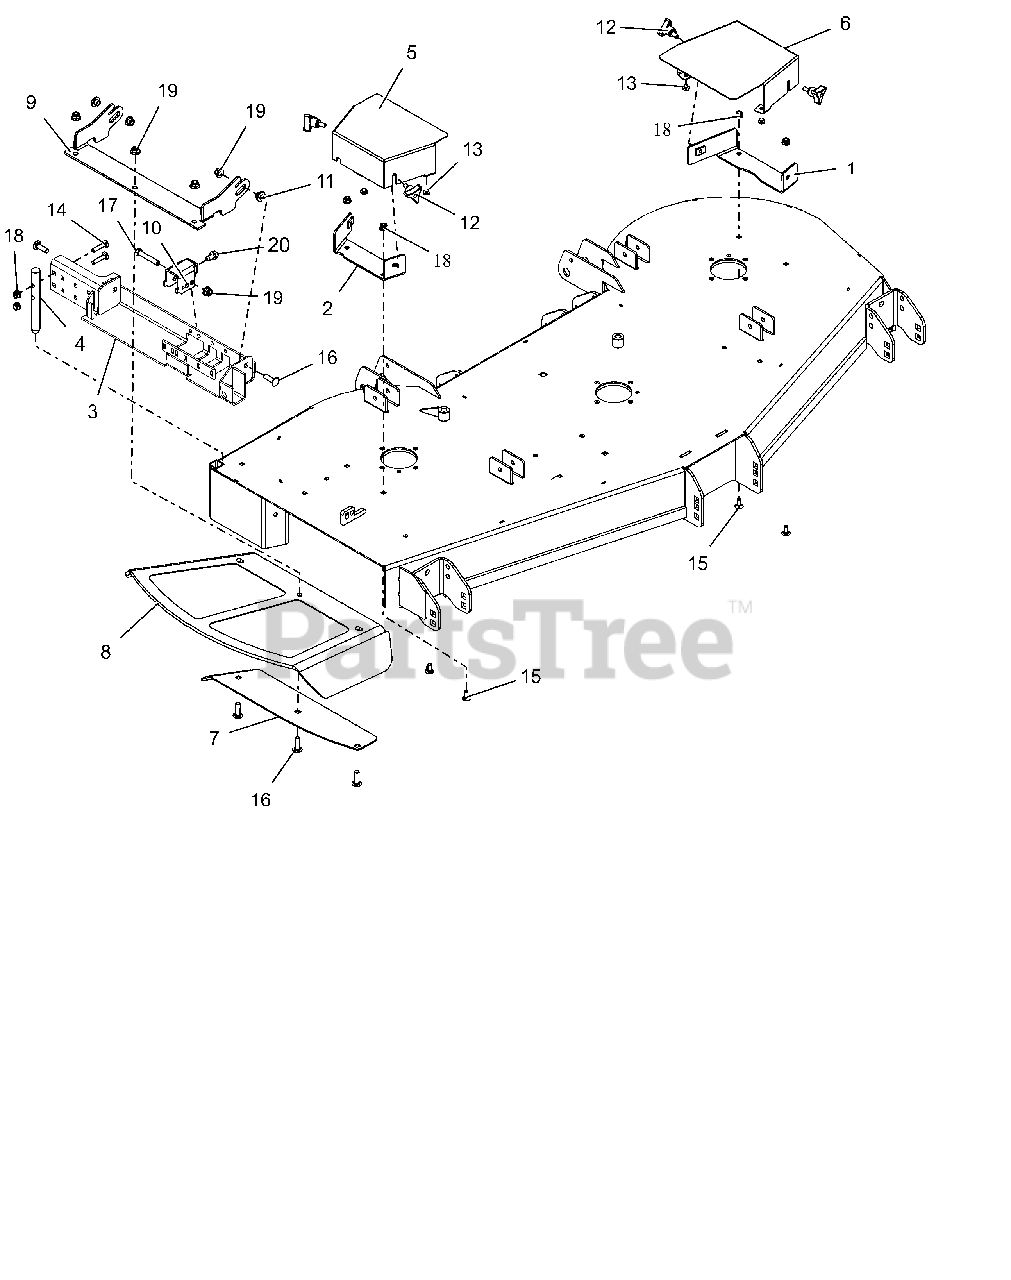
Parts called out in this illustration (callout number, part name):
1	BRKT, LH BELT GUARD MOUNTING
2	BRKT, RH BELT GUARD MOUNTING
3	WLDMT, GRASS CATCHER
4	PIN, DISCHARGE CHUTE X-DRILLED
5	GUARD, RH DECK BELT
6	GUARD, LH DECK BELT
7	48-60 DISCH CHUTE CLMP PLT-BLK
8	CHUTE,48-60" FRMD RUBBER DISCH
9	BRKT, 48-60" CHUTE MTG
10	BRKT, DISCH. CHUTE MTG
11	BSHG-FLG .385X.500X.875X.406
12	KNOB,WING STUD 5/16-18 X .75
13	BUMPER GROMMET
14	@BLT-RDHDSQNK .31-18X1.50 G5YZ
15	@BLT-RDHDSQNK .31-18X.75 G5YZ
16	@BLT-RHDSSQNK .38-16X1.25 G5YZ
17	@BLT-HEX .38-16X2.25 GR5 YWZC
18	@NUT-LK-NYL-FLG .31-18 YWZC
19	@NUT-LK-NYL-FLG .38-16 YWZC
20	@SCR-TAP .38-16X.75 HWH TR YWZ
